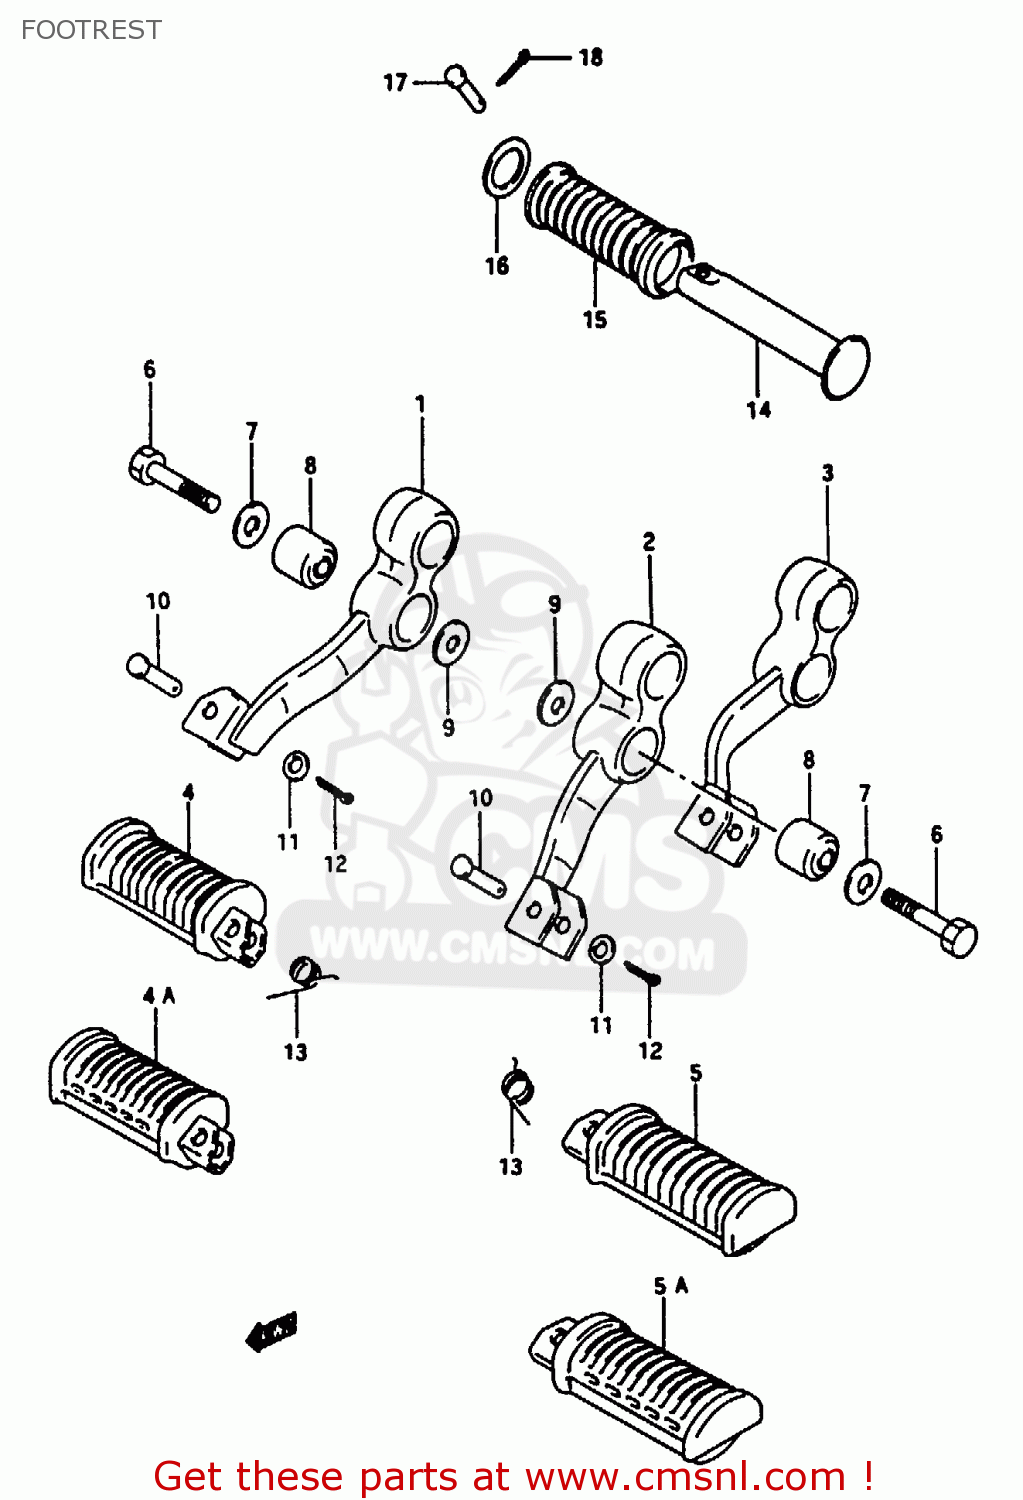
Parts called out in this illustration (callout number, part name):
1	BAR,FRONT FOOTREST
2	BAR,FR FOOTREST,L
3	BAR,FR FOOTREST,L
4	RUBBER,FRONT FOOTREST
4A	RUBBER,PILLION FOOTREST,R
5	FOOTREST
5A	RUBBER,PILLION FOOTREST,L
6	BOLT(10X35)
7	WASHER
8	BUSH
9	WASHER
10	PIN
11	WASHER
12	PIN 20X20
13	SPRING
14	BAR,PILLION FOOTREST
15	RUBBER,PILLION FOOTREST
16	WASHER (19.5X32X2)
17	PIN
18	PIN 20X20
